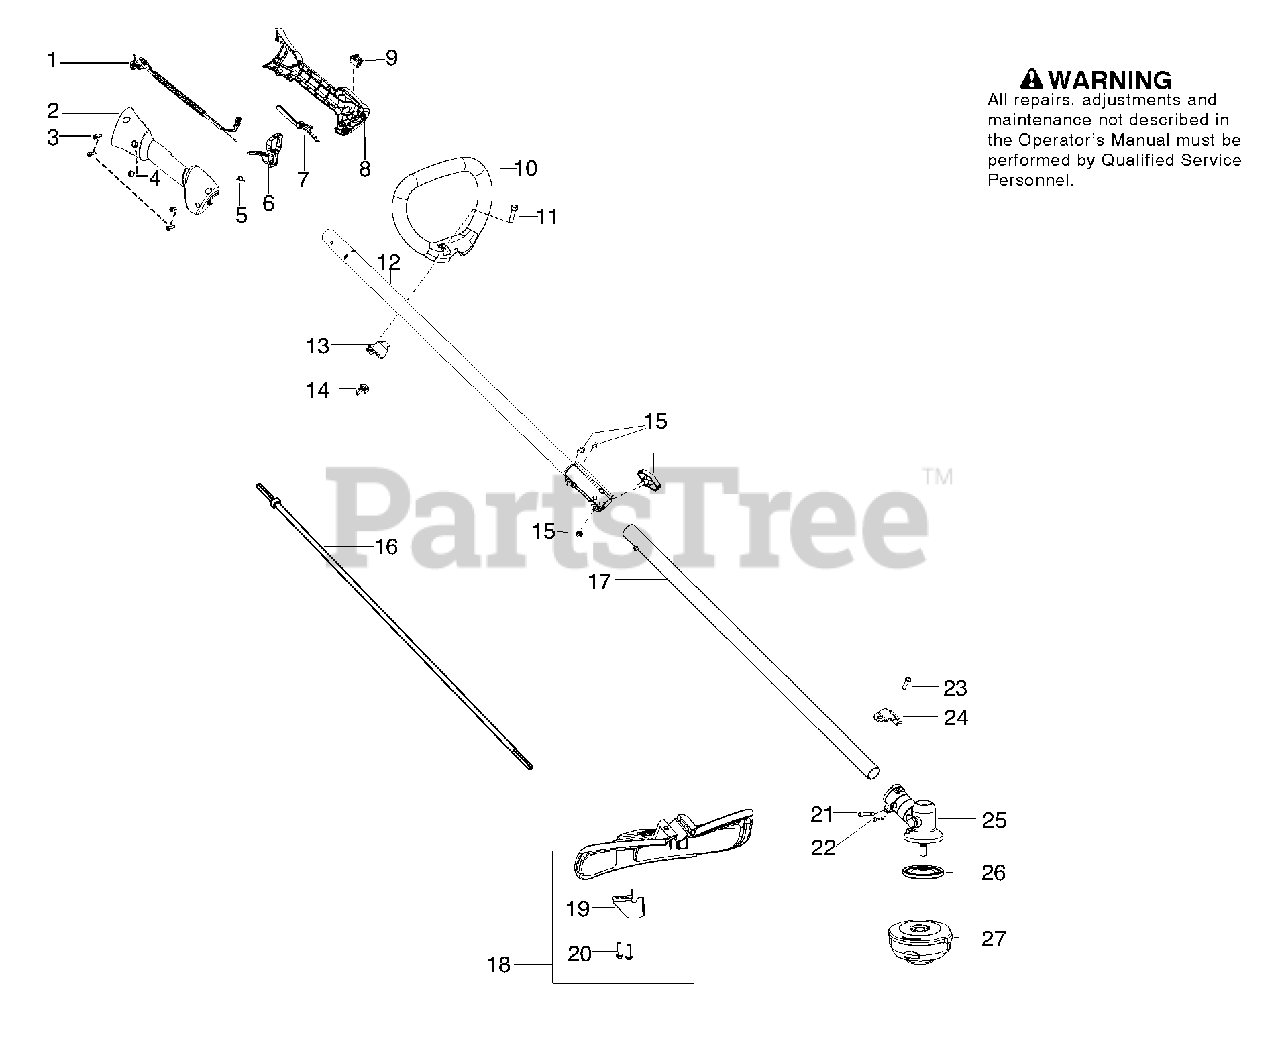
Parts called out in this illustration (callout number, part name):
1	Assy - Cable/Wire Harness
2	Housing - Throttle (RH)
3	Screw
4	Screw
5	Spring - Trigger
6	Trigger
7	Lockout - Throttle
8	Housing - Throttle (LH)
9	Kit - Switch
10	Handle - Assist
12	Kit - Driveshaft Upper
13	Clamp - Handle Assist
14	Wingnut
15	Kit -Knob / Screw
17	Kit - Lower Shaft
18	Kit - Shield
19	Limiter - Line
24	Bracket - Shield
25	Assy - Gearbox
26	Driver Disc
27	Assy - T25 Cutting Head
